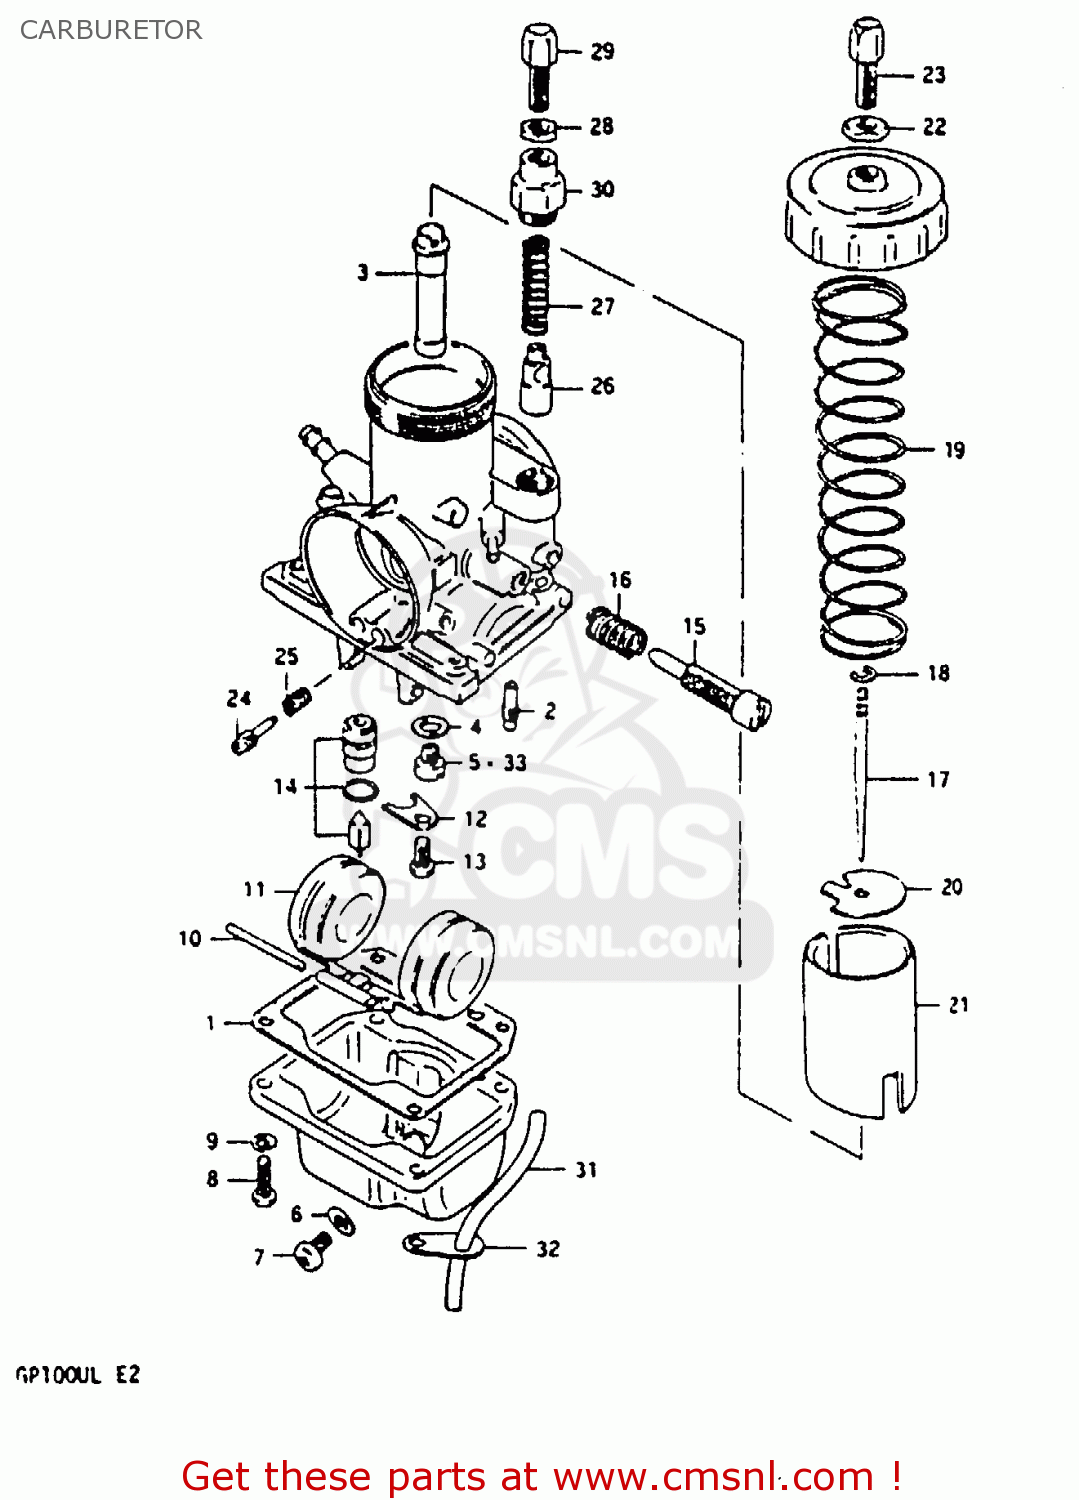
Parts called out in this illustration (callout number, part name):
1	GASKET,FLOAT CAHMBER (NAS)
2	JET,PILOT(25)
3	JET,NEEDLE
4	WASHER,NEEDLE NOZZLE
5	JET,MAIN(105)
6	GASKET,DRAIN,PLUG (NAS)
7	PLUG
8	SCREW
9	LOCK WASHER
10	PIN,FLOAT
11	FLOAT
12	PLATE
13	SCREW
14	VALVE ASSEMBLY,NEEDLE
15	SCREW,THROTTLE STOP
16	SPRING,THROTTLE SCREW
17	NEEDLE,JET
18	CLIP
19	SPRING,THROTTLE VALVE
20	PLATE
21	VALVE,THROTTLE
22	NUT
23	ADJUSTER,CABLE
24	SCREW,PILOT AIR
25	SPRING
26	PLUNGER,STARTER
27	SPRING
28	NUT
29	ADJUSTER,CABLE
30	CAP
31	HOSE
32	PLATE
33	JET,MAIN
